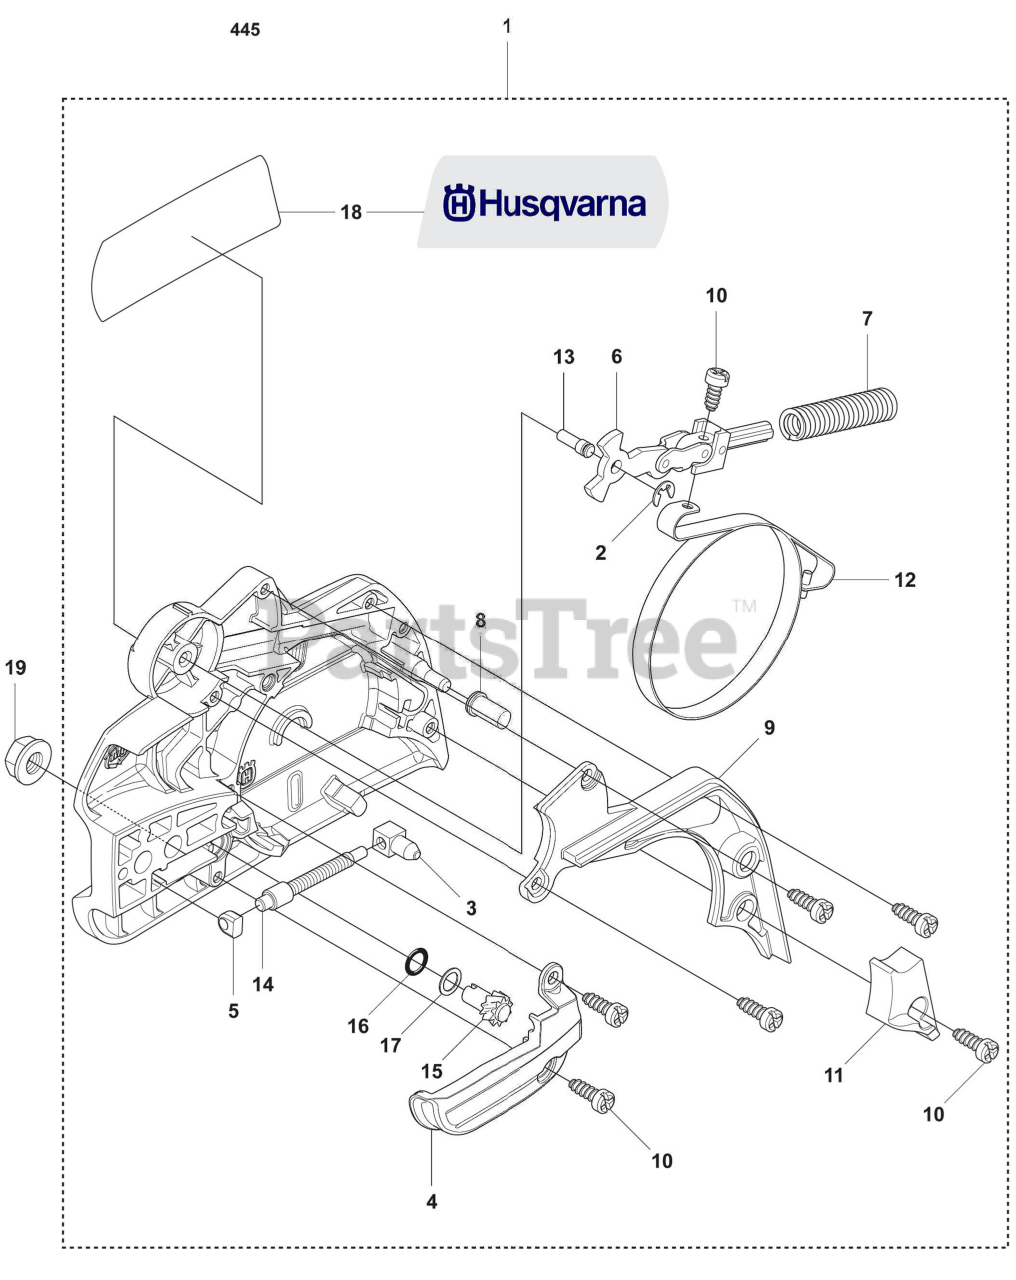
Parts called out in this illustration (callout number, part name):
1	Clutch Cover Assembly
2	Bar Retainer
4	Chain Guide
9	Chain Brake Cover
11	Chain Wear Guard
12	Brake Band
14	Worm Screw
15	Worm Wheel
18	Label, 400 Series
19	Flange Hex Nut, M8
